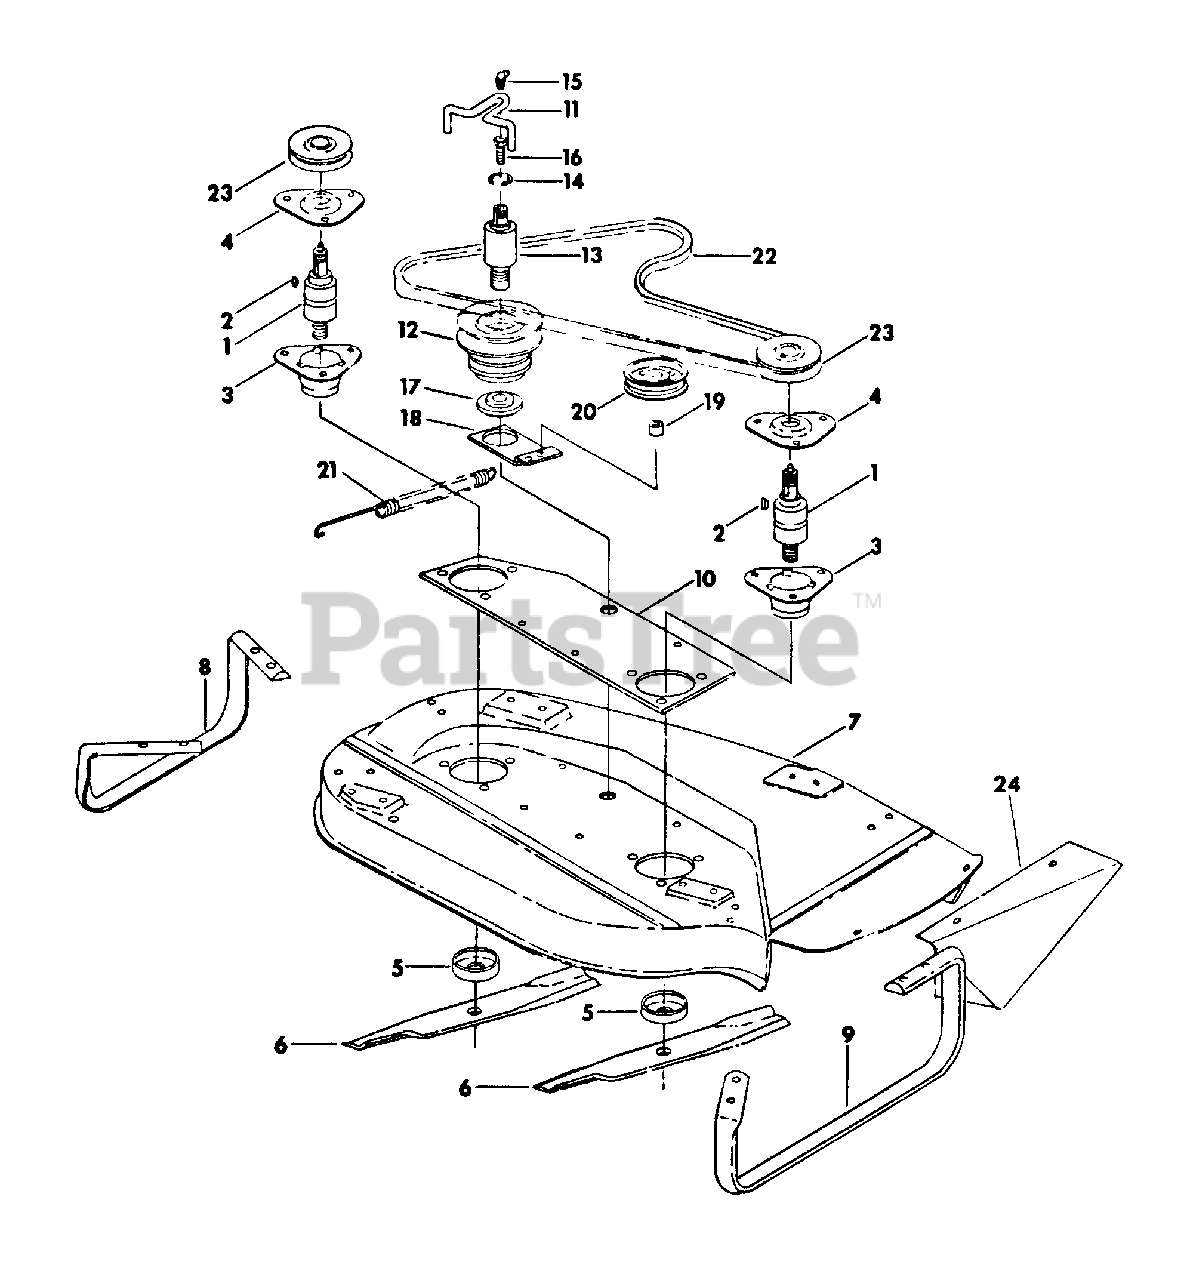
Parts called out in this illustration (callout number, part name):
1	BEARING, BALL AND FAN TYPE
2	KEY, 1/4 X 3/4 WOODRUFF 91
3	HOUSING, SPINDLE
4	CAP, SPINDLE HOUSING
5	CUP, SPINDLE
6	BLADE, 32 IN. MOWER
7	HOUSING ASSY, 32 IN MOWER
8	RUNNER, LH MOWER
9	RUNNER, RH MOWER
10	PLATE, SPINDLE MTG
11	GUIDE, PTO BELT
12	PULLEY, CENTER SPINDLE
13	BEARING, FAN AND WATER PUMP TYPE
14	RING, 2.072 INT RET
15	FITTING, 3/8 45 DEG DRIVE TYPE LUB
16	BOLT, END
17	SPACER, PULLEY
19	SPACER, IDLER PULLEY
20	IDLER, BALL BRG
21	SPRING, IDLER
22	BELT, BLADE DRIVE
23	PULLEY, BLADE
24	SHIELD, DEFLECTOR 32 IN.
